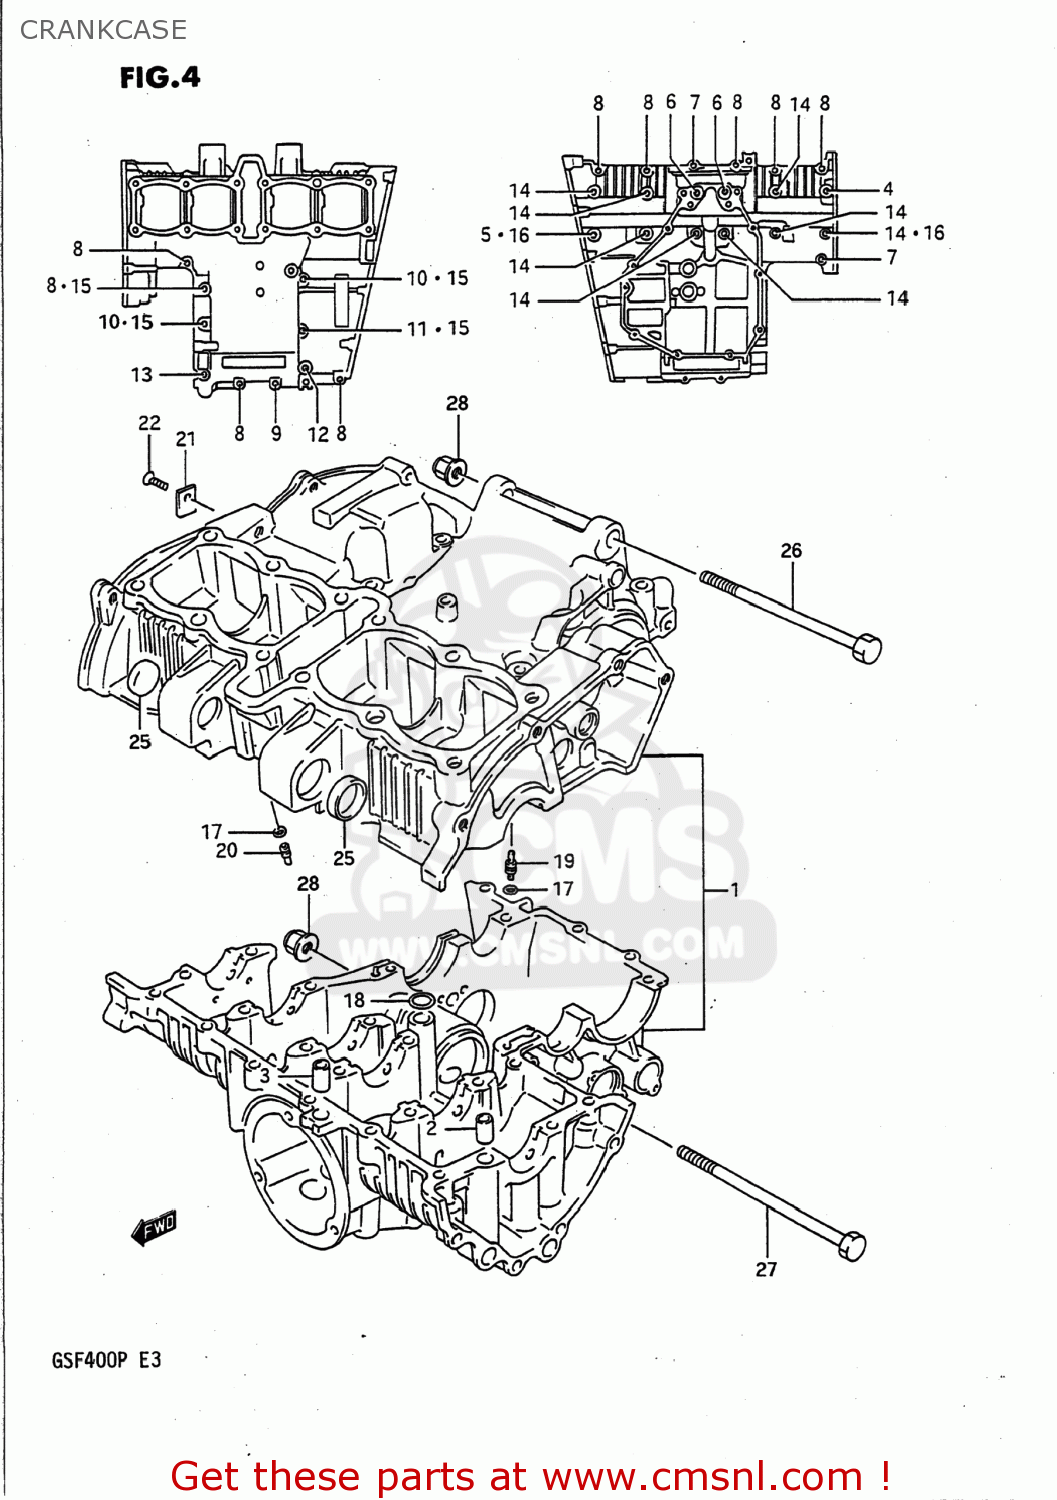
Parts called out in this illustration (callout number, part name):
1	CRANKCASE SET
2	PIN (11X20)(SUS)
3	PIN(10.4X13X22)
4	BOLT
5	BOLT(8X105)
6	BOLT
7	BOLT 6X30
8	BOLT 6X35
9	BOLT (6X45)
10	BOLT 6X55
11	BOLT
12	BOLT
13	BOLT
14	BOLT(8X95)
15	GASKET(6.2X13X1.2) (NAS)
16	GASKET(8.2X14X1) (NAS)
17	O RING(D:1.2,ID:4)
18	O RING(D:1.9,ID:13)
19	JET(8)
20	JET,OIL
21	PLATE,OIL GALLERY PLUG
22	SCREW
23	PLATE,CRANK THRUST
24	PLATE,CRANK THRUST
25	PLUG
26	BOLT 10X135
27	BOLT 10X145
28	NUT (10MM)
